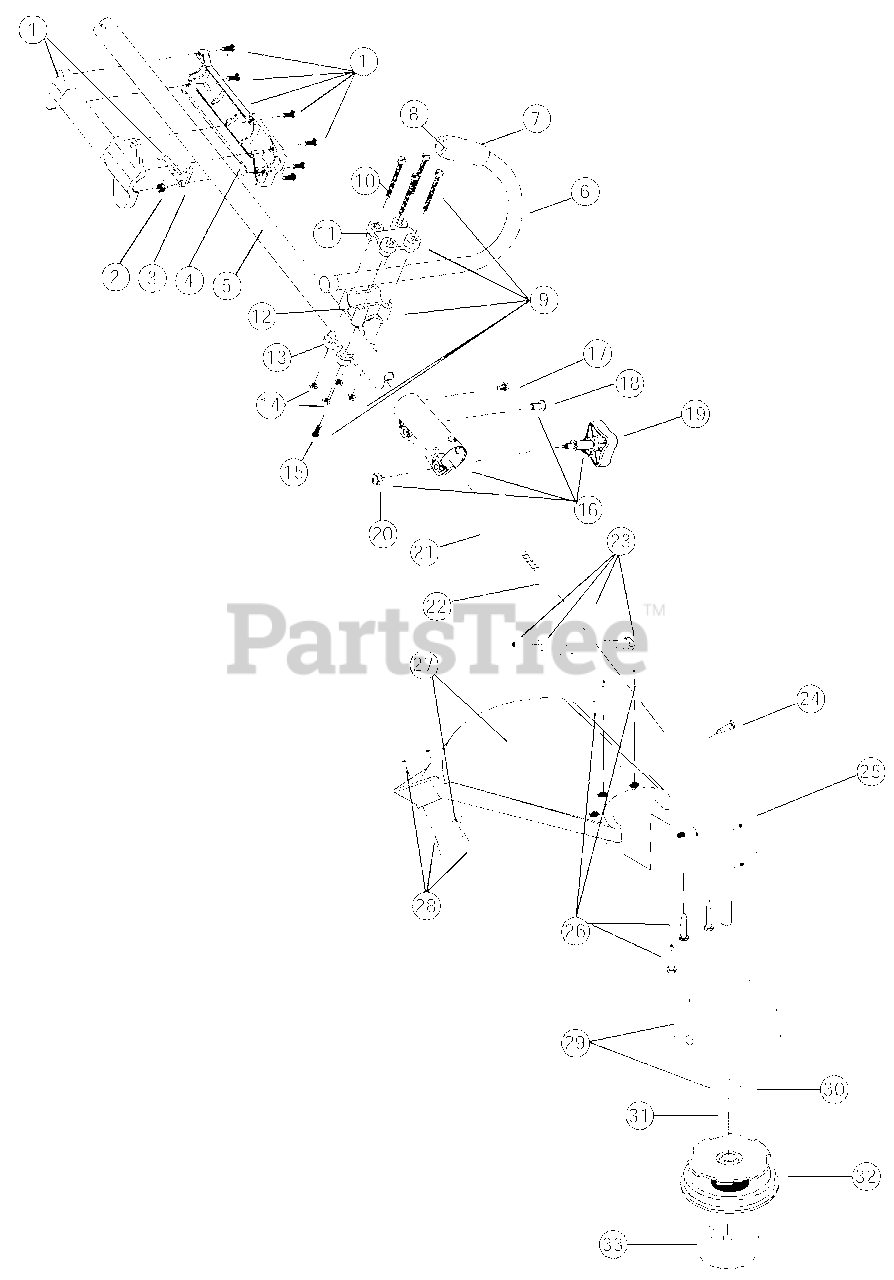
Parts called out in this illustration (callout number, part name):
1	Throttle Housing & Trigger Assembly
2	Throttle Trigger Spring
3	Throttle Trigger
4	Throttle Cable Assembly
5	Upper Drive Shaft Housing Assembly
6	J-Handle Assembly
8	Tube Closure
9	Handle Bracket Assembly
11	Upper Handle Clamp
12	Middle Handle Clamp
13	Lower Handle Clamp
15	Anti-Rotation Screw
16	Click-Link Coupler
19	Adjustment Knob
20	Knob Retaining Nut
21	Lower Drive Shaft Housing Assembly
22	Lower Flexible Drive Shaft
23	Lower Clamp Assembly
24	Anti-Rotation Screw
25	Gearbox Assembly
26	Shield Mounting Hardware
27	Shield and Blade Assembly
28	Blade Assembly
29	Outer Spool and Eyelet Assembly
30	Retainer
32	Inner Reel
33	Bump Head Knob Assembly
